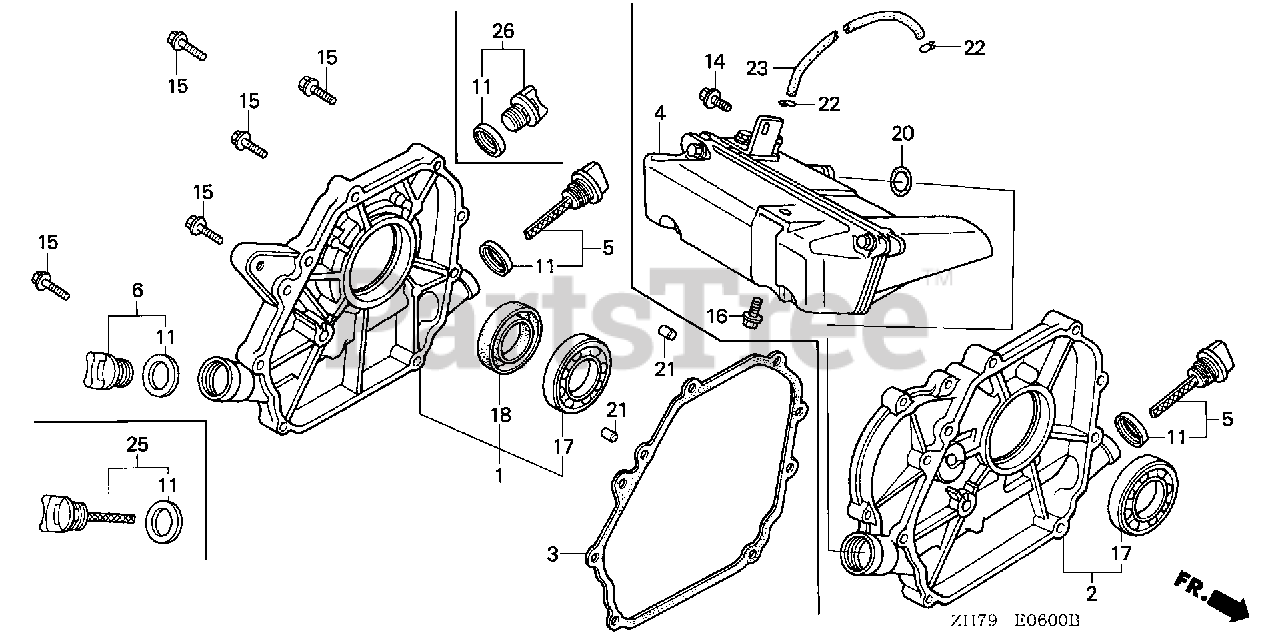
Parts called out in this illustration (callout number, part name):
1	COVER ASSY., CRANKCASE (W-TYPE)
3	GASKET, CASE COVER
5	CAP ASSY., OIL FILLER
6	CAP ASSY., OIL FILLER
11	GASKET, OIL FILLER CAP
15	BOLT, FLANGE (6X28)
17	BEARING, RADIAL BALL (62/22)
18	OIL SEAL (22X41X6)
21	PIN A, DOWEL (8X14)
